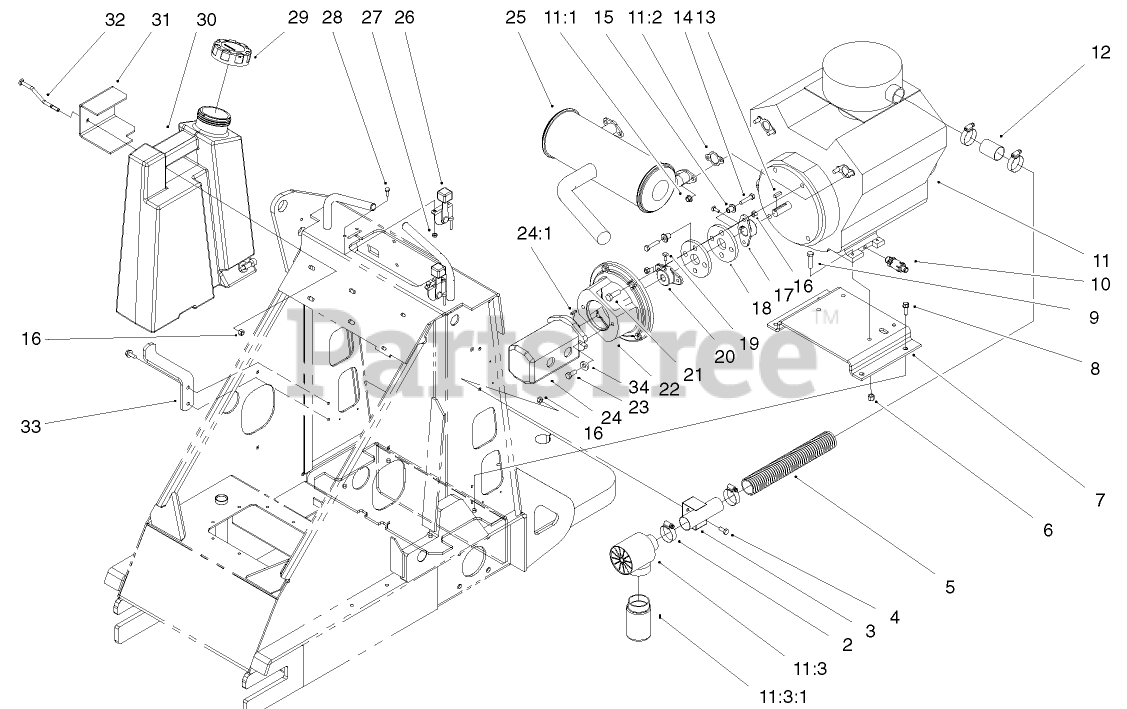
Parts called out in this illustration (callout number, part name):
3	WA - TUBE
4	SCREW-HH
5	HOSE - AIR
6	NUT-LOCK, NI
7	Mount-Engine
8	SCREW-TAPTITE
9	SCREW-HH
10	VALVE-DRAIN, OIL
11	Engine (CH22S 66551) Kohler 22 Hp.
11:1	NUT-HF
11:2	GASKET-EXHAUST
11:3	PRECLEANER - KOHLER F/W
11:3:1	JAR - PRECLEANER
12	TUBE - AIR
13	KEY-SQUARE
14	SCREW-HH
15	SPACER
16	NUT-LOCK, NI
17	HUB-ENGINE
18	COUPLING-RUBBER
19	SCREW-SET
20	HUB-PUMP
21	SCREW-HH
22	Mount-Pump
23	SCREW-HSH
24	PUMP-GEAR, TANDEM
24:1	KEY-SQUARE
25	Muffler-Kohler 22
26	CONTROL-CHOKE / THROTTLE
27	NUT-LOCK, NI
28	SCREW-HHF
29	GAS CAP ASM
30	Fuel Tank ASM
31	Plate
32	BOLT-MOUNT
33	Mount-Tank
34	WASHER-FLAT
